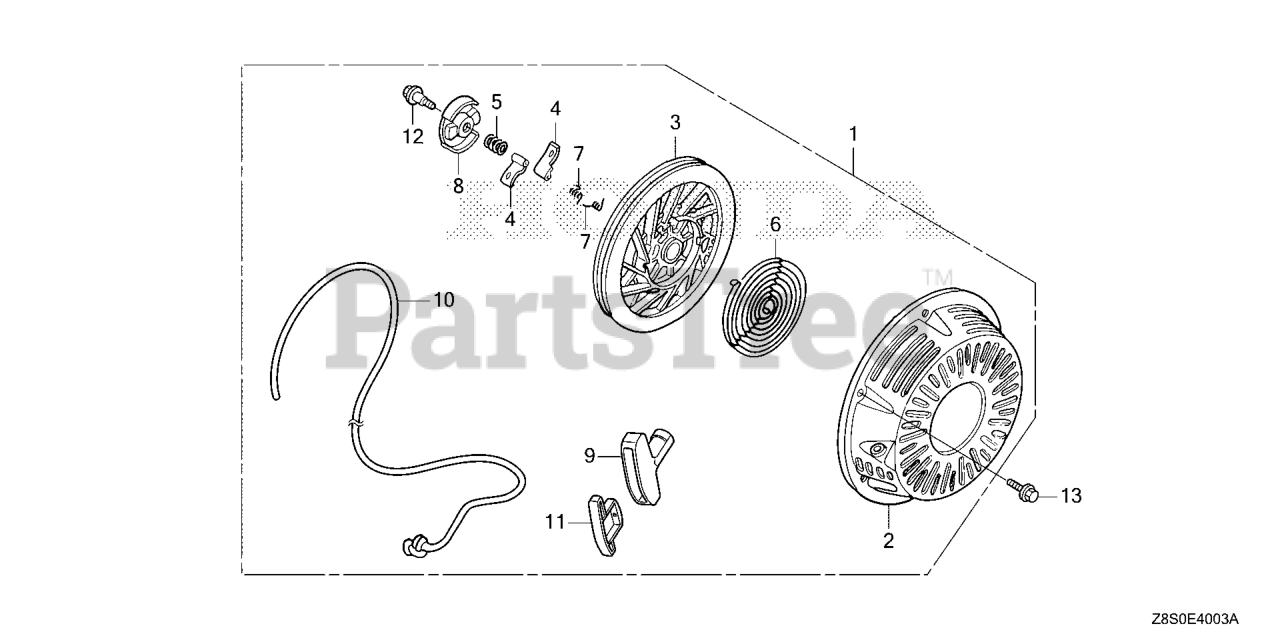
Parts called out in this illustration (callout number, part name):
1	STARTER ASSY., RECOIL *NH1* (COO)(FOR U.S.A.) (BLACK)
2	CASE, RECOIL STARTER *NH1* (BLACK)
3	PULLEY, RECOIL STARTER
4	RATCHET, STARTER
5	SPRING, FRICTION
6	SPRING, STARTER RETURN
7	SPRING, RATCHET
8	RETAINER, SPRING
9	GRIP, STARTER
10	ROPE, RECOIL STARTER (#5X55")
11	GRIP, REINFORCEMENT
12	SCREW, CENTER
13	BOLT, FLANGE (6X10)
